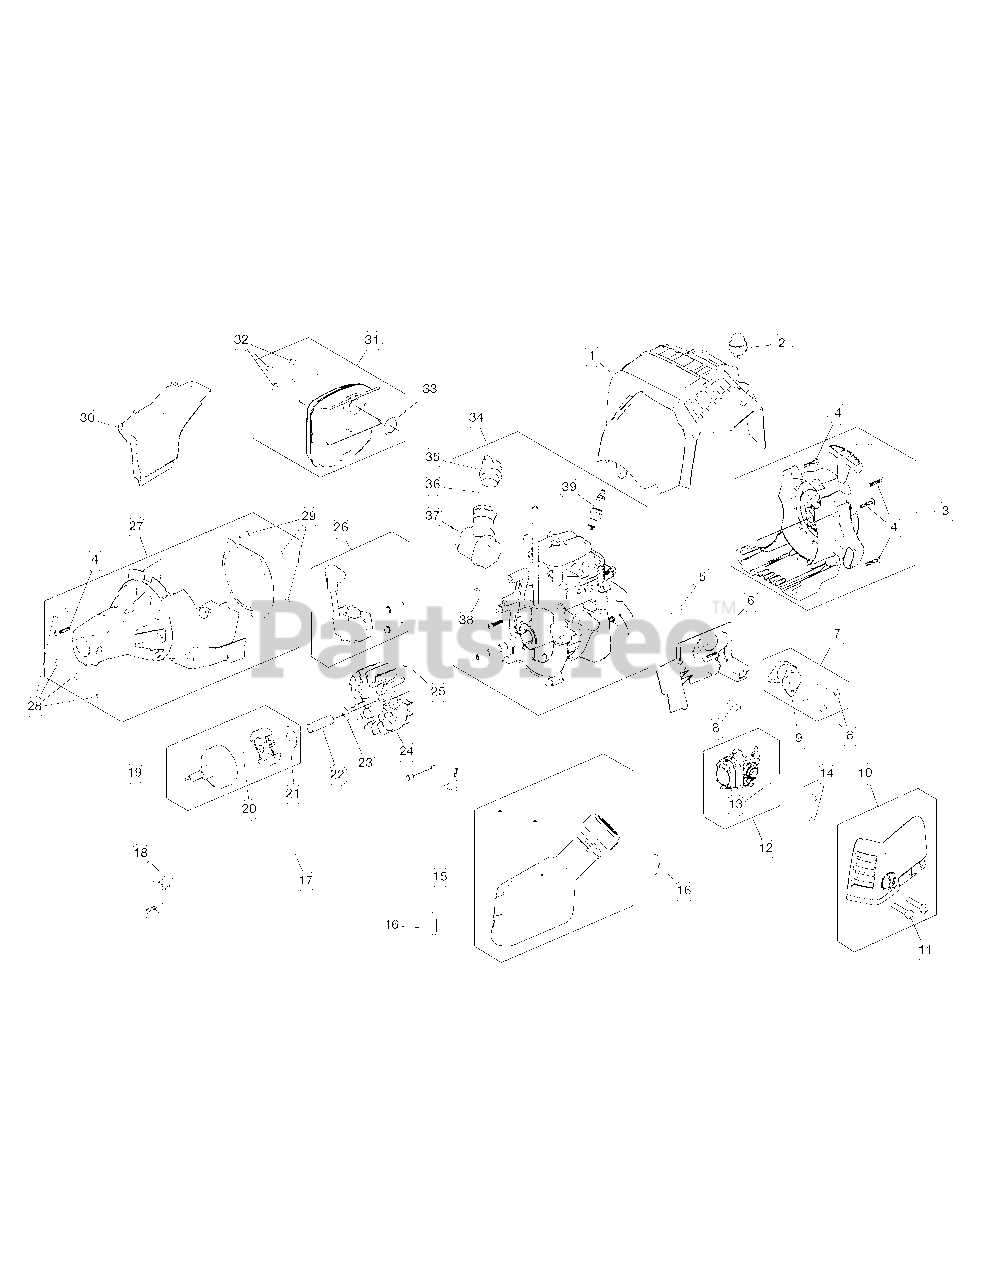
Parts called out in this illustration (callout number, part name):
1	Top Housing
2	Air Purge Primer
3	Starter Housing Assembly (Incl. 4)
5	O-Ring
6	Intake Port
7	Boot Assembly (Incl. 8 & 9)
8	Screw
10	Air Cleaner Assembly
12	Carburetor Assembly (Incl. 13)
15	Fuel Tank Assembly
16	Fuel Tank Pad
17	Lead Wire
18	Throttle Cable
19	Clutch Assembly (Incl. 20 & 21)
20	Thrust Washer
21	Clutch Washer
22	Spacer
23	Washer
24	Flywheel
26	Module Assembly
27	Clutch Cover Assembly (Incl. 28 & 29)
28	Screw
29	Screw
30	Rear Engine Cover
31	Muffler Assembly (Incl. 32 & 33)
33	Muffler Gasket
34	Shortblock Assembly (Incl. 35 - 39)
35	Oil Fill Plug
36	O-Ring
37	Oil Fill Tube Assembly
38	Screw
39	Spark Plug
